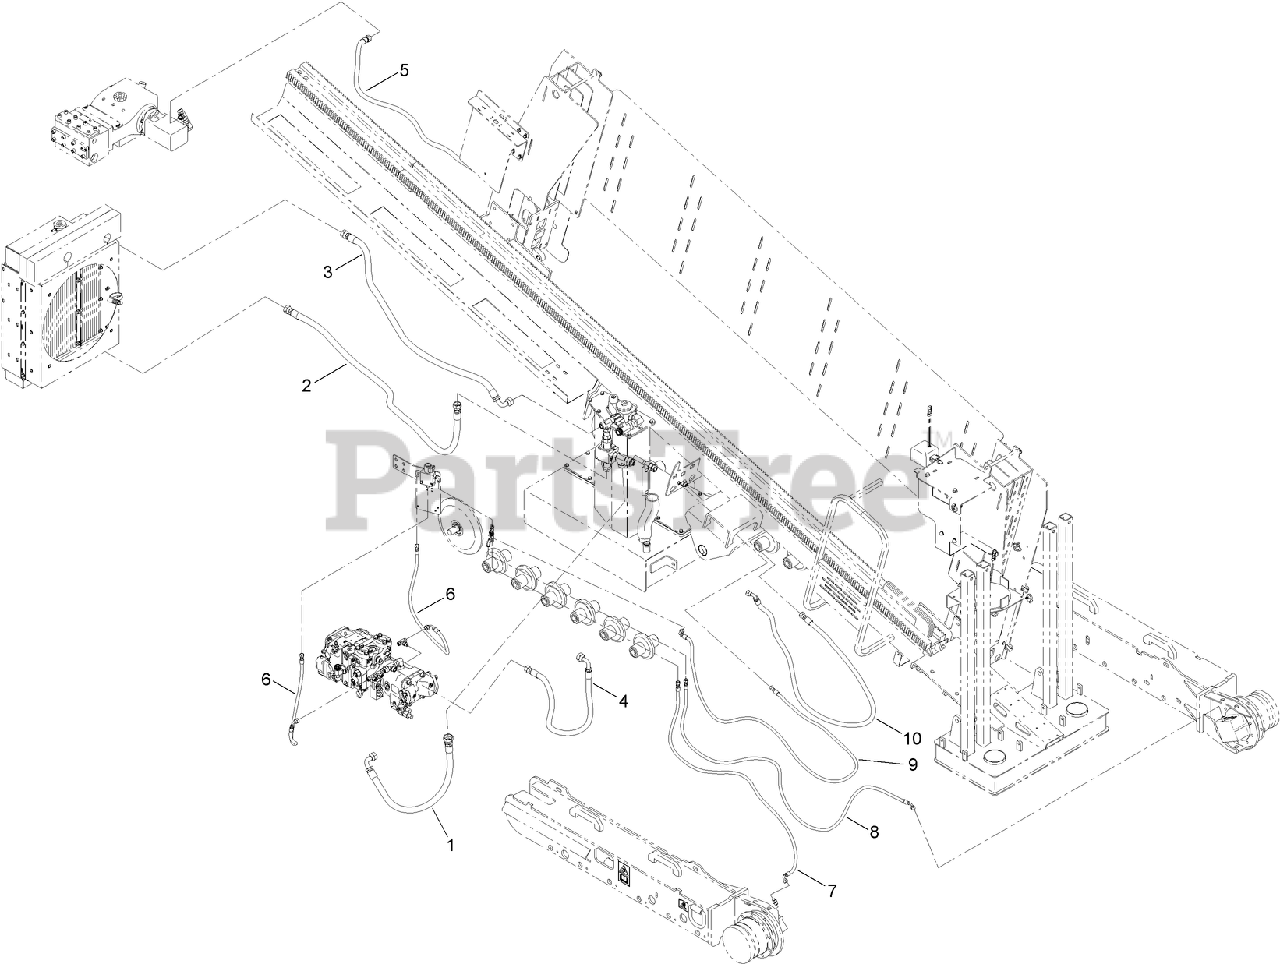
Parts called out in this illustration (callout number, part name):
1	HOSE ASM
2	HOSE ASM
3	HOSE ASM
4	HOSE ASM
5	HOSE ASM
6	HOSE ASM
7	HOSE ASM
8	HOSE ASM
9	HOSE ASM
10	HOSE ASM
